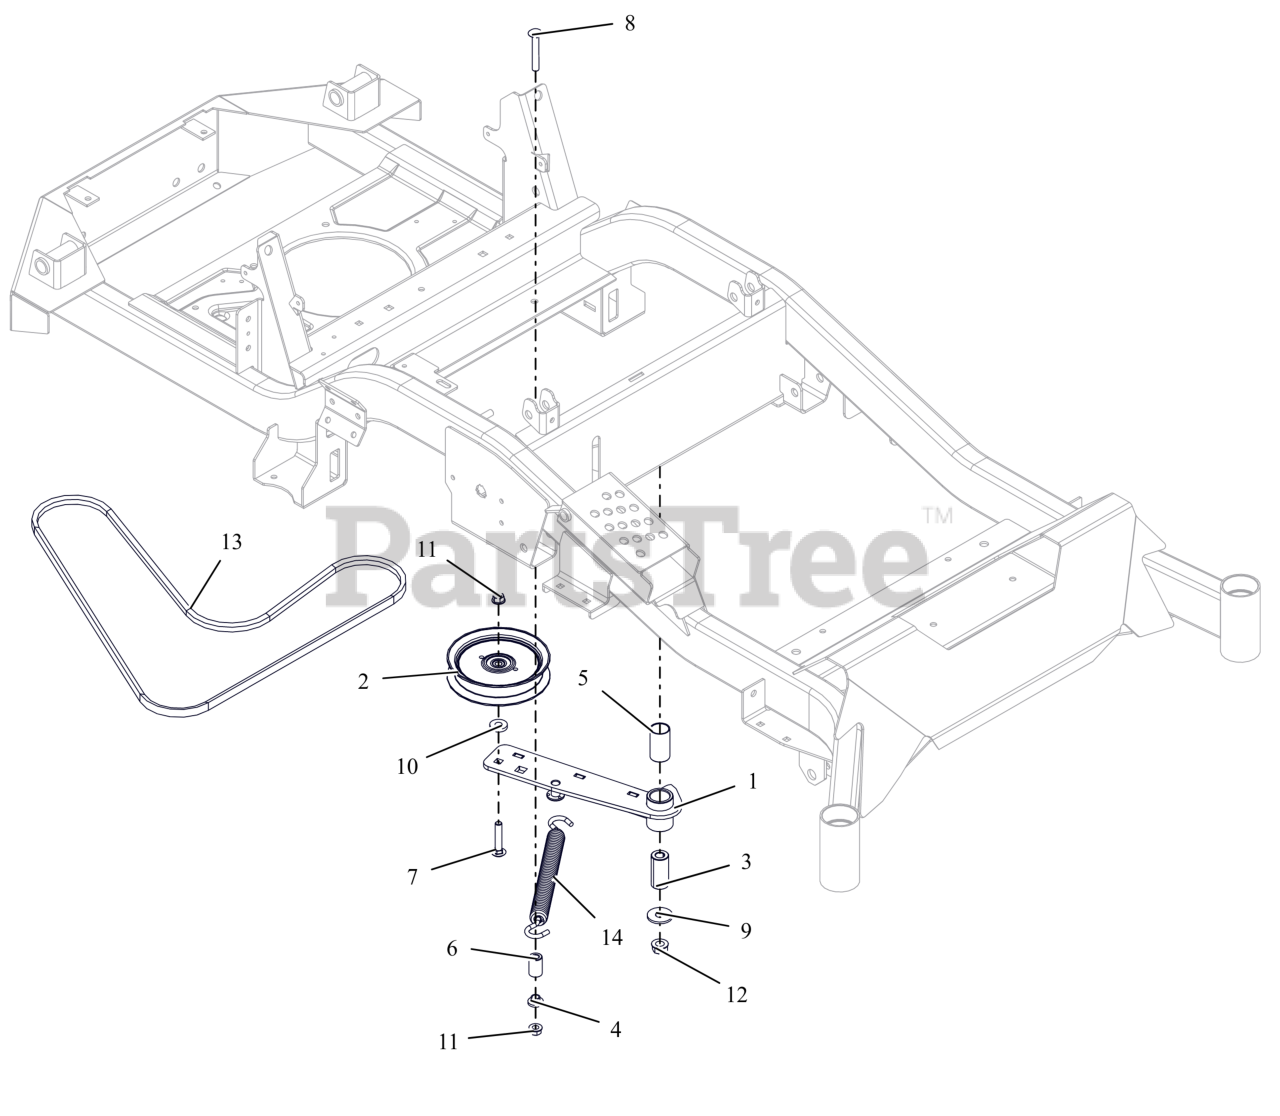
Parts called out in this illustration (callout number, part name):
1	WLDMT, HYDRO DRIVE IDLER ARM (BLACK)
2	IDLER, FLAT 5.00"
3	BSHG, SPCR .502X.997X2.03 PM
4	BSHG-FLG .385X.500X.875X.406
5	BSHG, 1.00X1.125X1.937
6	BUSHING, SLV .380X.750X1.190
7	BLT, RHSN .38-16X2.00 G5 ZCC
8	BLT, RHSSN.38-16X2.50 G5 ZCC
9	WSHR-FL-STL.511X1.44X.125ZC120
10	WSHR, FLT .406X1.00X.188 ZCC
11	NUT-LK-TOP-FLG .38-16 ZC120
12	NUT-LK-TOP-FLG .500-13 GF ZCC
13	V-BELT, 4L-WRAPPED
14	SPRING, EXTENSION
